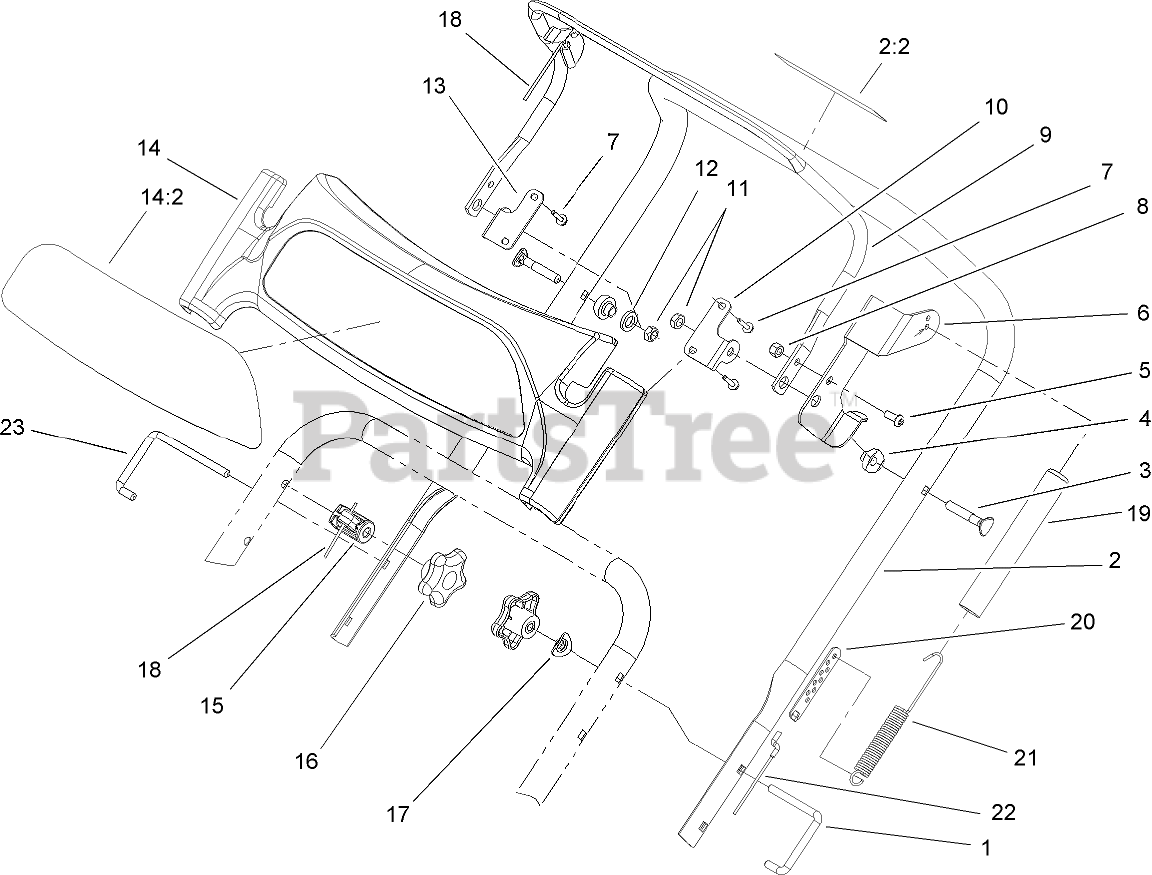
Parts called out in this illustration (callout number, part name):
1	LOCK-HANDLE
2	UPPER HANDLE ASM
2:2	DECAL-DRIVE, ROTOR
3	SCREW-HANDLE
4	SPACER-BAR, CONTROL
5	SCREW-HSBH
6	ARM-CLUTCH, HANDLE
7	SCREW-HWH
8	NUT-LOCK, NI
9	BAR-CONTROL
10	BRACKET-PANEL, LH
11	NUT-LOCK, NI
12	WASHER
13	BRACKET-PANEL, RH
14	DISPLAY HANDLE PANEL ASM
14:2	Decal-Display, Handle
15	GUIDE-Cable, PIVOT
16	KNOB-HANDLE
17	WASHER
18	CABLE-PIVOT
19	COVER-SPRING
20	ADJUSTER-CABLE, CLUTCH
21	SPRING-CABLE
22	CABLE-CLUTCH
23	LOCK-HANDLE, RH
